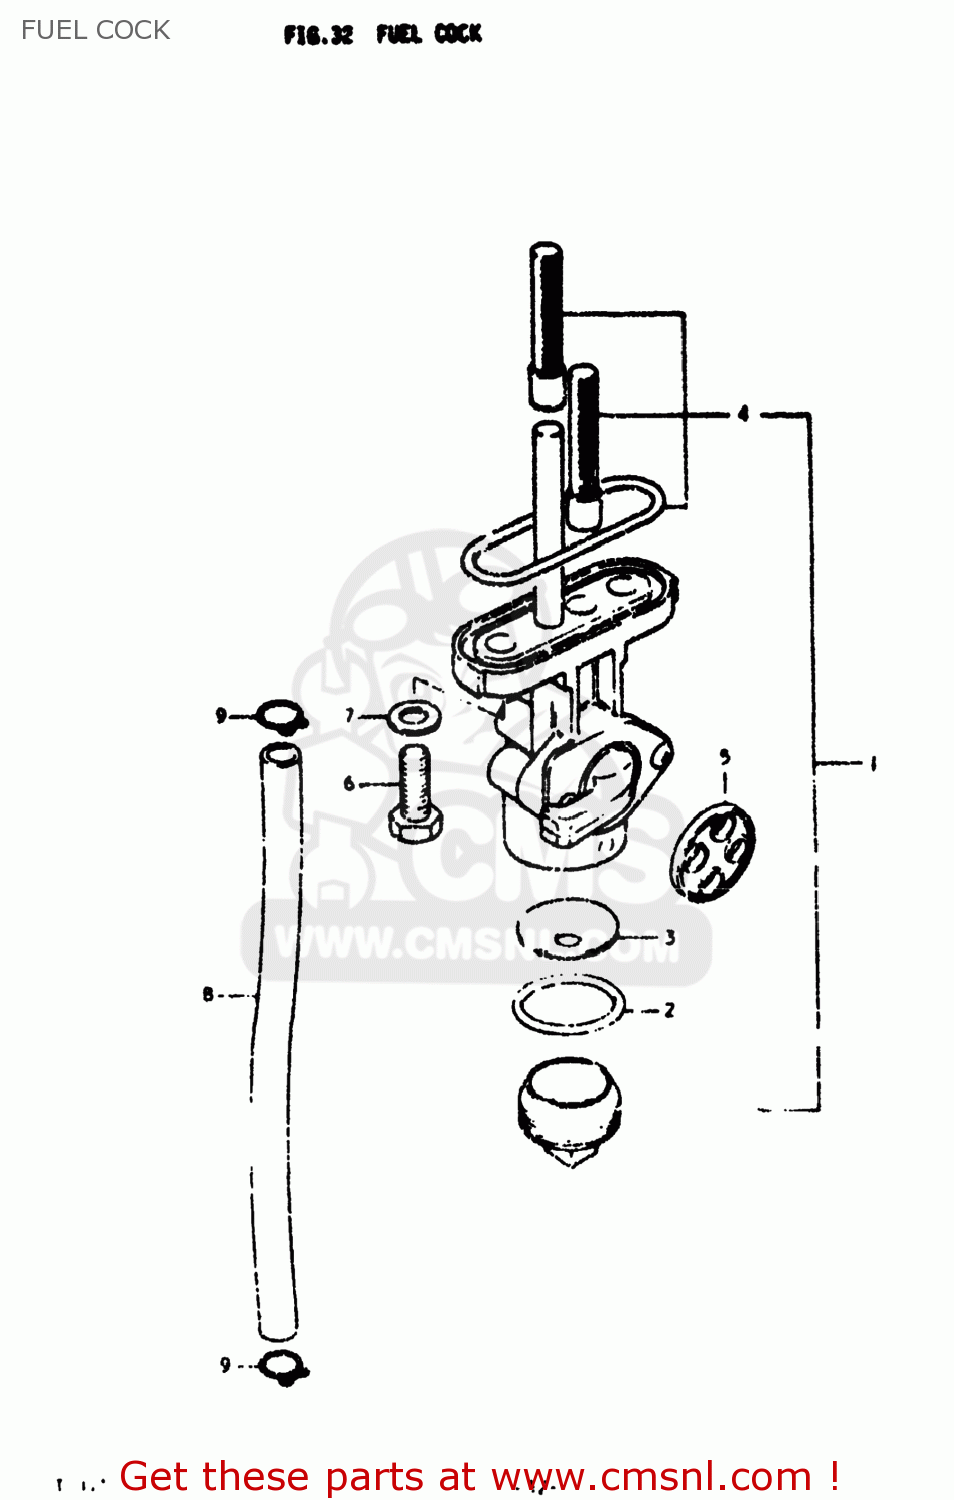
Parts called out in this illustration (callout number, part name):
1	COCK ASSEMBLY,FUEL
2	GASKET,FILTER (NAS)
3	NET,STRAINER
4	FILTER SET,FUEL COCK
5	GASKET,LEVER (NAS)
6	SCREW
7	GASKET
9	CLIP
